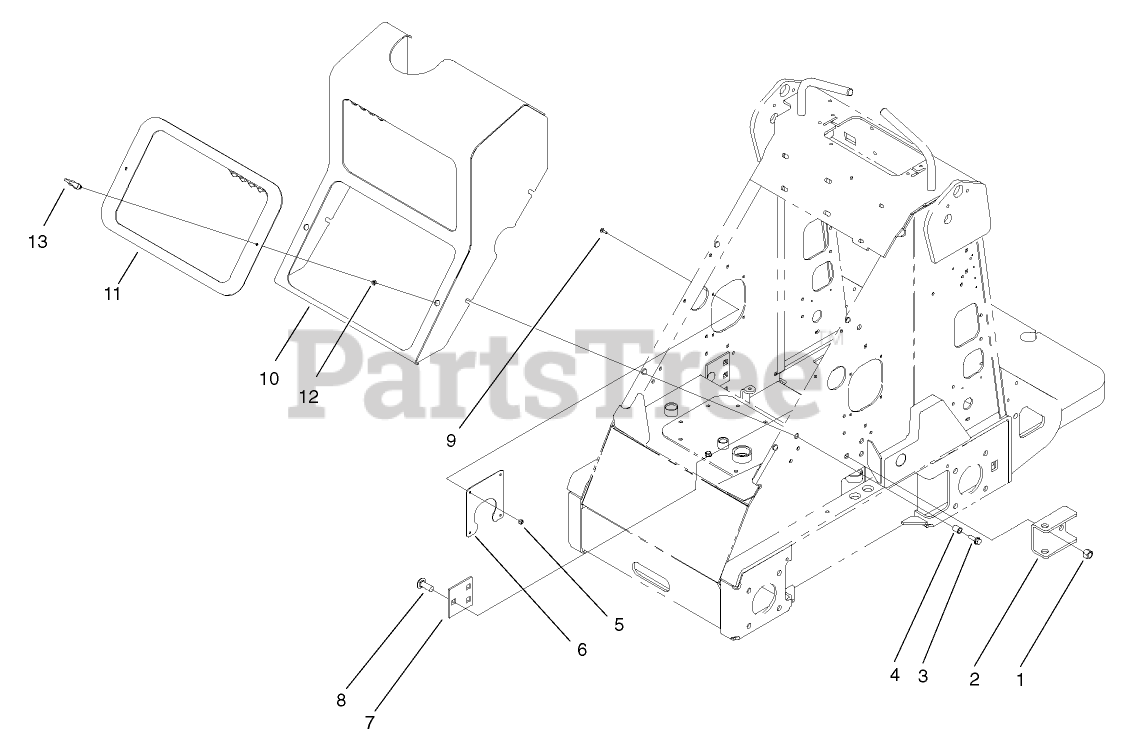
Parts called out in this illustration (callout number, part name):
1	NUT-LOCK, NI
2	BRACKET-ANCHOR
3	SCREW-HHF
4	INSERT-THREADED
5	NUT-LOCK, NI
6	GUARD-MUFFLER
7	PLATE-ANCHOR
8	SCREW-CARR, SHORT NECK
9	SCREW-CARR
12	WASHER
13	LATCH-SWELL
